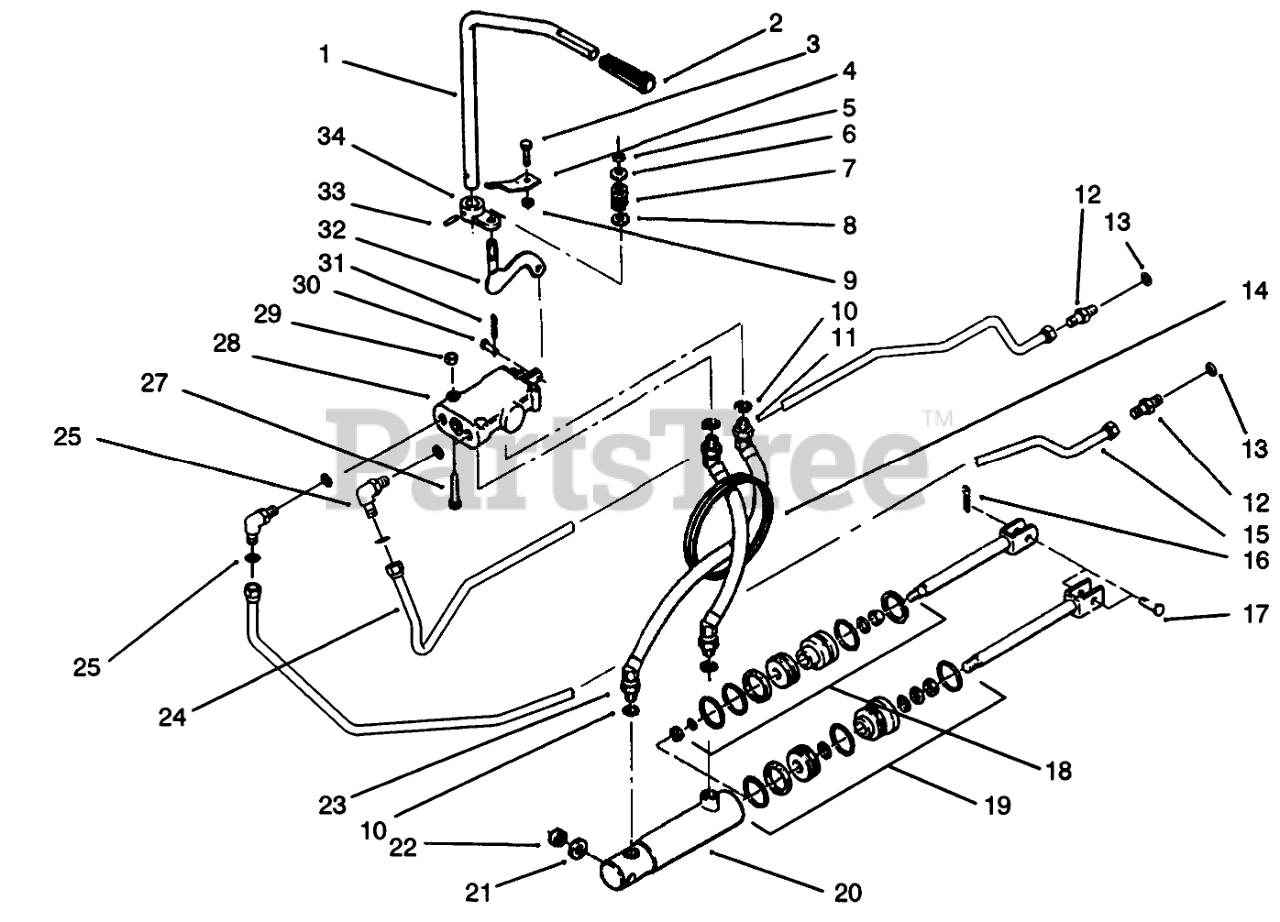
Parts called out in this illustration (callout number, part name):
1	ROD-LIFT CONTROL
2	KNOB-HYDRAULIC LIFT
3	SCREW-HH
4	BRACKET-CONTROL R B
5	NUT-LOCK, NI
7	SPRING
8	SCREW-HH
9	NUT-LOCK, NI
10	O RING
11	Hose ASM-Hydraulic
12	FITTING
13	0-Ring
14	GROMMET
15	TUBE-HYD RETURN
16	PIN-COTTER
17	CLEVIS PIN
18	S/A O-RING&GASKET AS
19	S/A 108872 HYD CYL
20	Cylinder-Hydraulic (Incl. Ret. #18-19)
21	SPACER-WORM SHAFT
22	WASHER
23	Hose ASM-Hydraulic
24	TUBE-HYD RETURN
25	ELBOW
27	SCREW-HH
28	Valve-Hydraulic (Incl.Ref. #30-31)
29	NUT-LOCK, NI
30	Pin
31	Cotter Pin
32	WLDMT-LIFT BAR
34	ARM-CONTROL
